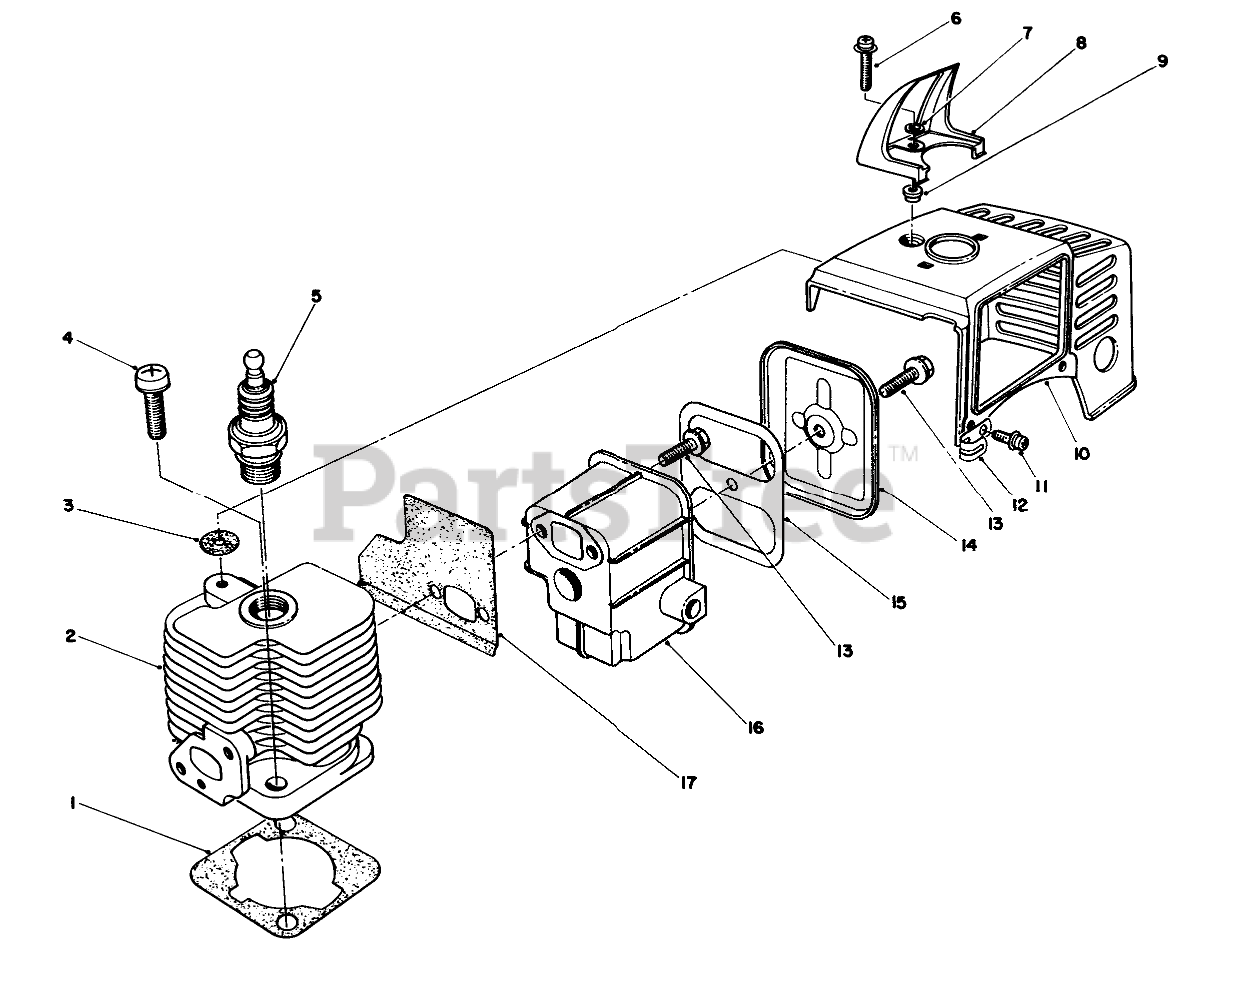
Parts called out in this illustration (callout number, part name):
1	CYL. GASKET
2	CYLINDER
3	GASKET
5	SPARK PLUG (NGK)
6	SCREW W/ WASHER
7	Washer
8	COVER
9	Bushing
10	TOP COVER
11	Screw
12	CLAMP
14	Lid-Muffler
15	MUFFLER GASKET
16	MUFFLER BODY
17	MUFFLER GASKET
